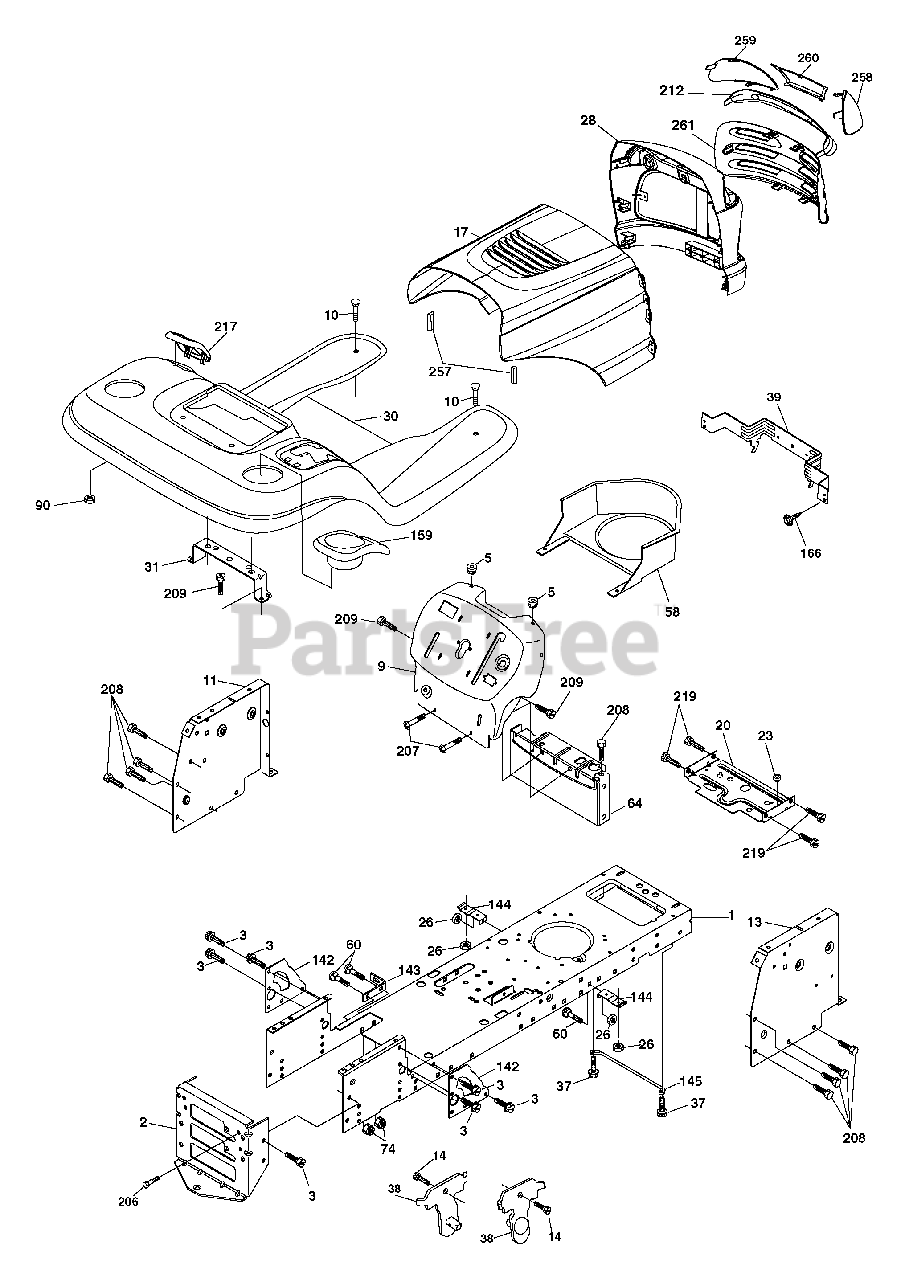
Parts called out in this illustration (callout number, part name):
1	Chassis Stamping
3	Screw 3/8-16 x 3/4
9	Dashboard
10	Bolt Rdhd Sqnk 3/8-16 Unc x 1
11	Panel Dash Lh
12	Clip Tinnerman Grille
13	Panel Dash Rh
14	Screw Thdrol 3/8-16 x 1/2
17	Hood
18	Bumper Hood
20	Plate Mtg Battery/Fuel Tank
26	Nut Lock w/Insert 3/8-16 Unc
28	Grille Lens Asm
30	Fender
37	Screw Thdrol 5/16-18 x 1/2
38	Bracket Asm Pivot Mower Rear
39	Bracket Pivot Hood
60	Bolt RDHD SQNK 3/8-16 x 3/4
64	Dash Lower Stlt
74	Nut Crownlock 3/8-16
142	Plate Reinforcement Stlt
143	Bracket Swaybar Chassis
144	Bracket Ft Rest
145	Rod Pivot Chassis Hood
159	Cupholder YTGT Grey
166	Screw Hw Hd Hi-Lo #13-16 x 3/4
206	Bolt Shoulder 5/16-18 TT
207	Screw Thdrol 5/16-18 x 1/2 TYTT
208	Screw Thdrol 3/8-16 x 1/2 Ty-TT
209	Screw 3/8-16 x 3/4
212	Insert Lens Reflect
217	Fuel Window
219	Screw 5/16-18 x 3/4
258	Lens RH
259	Lens LH
260	Cover Lens
261	Insert, Grille
